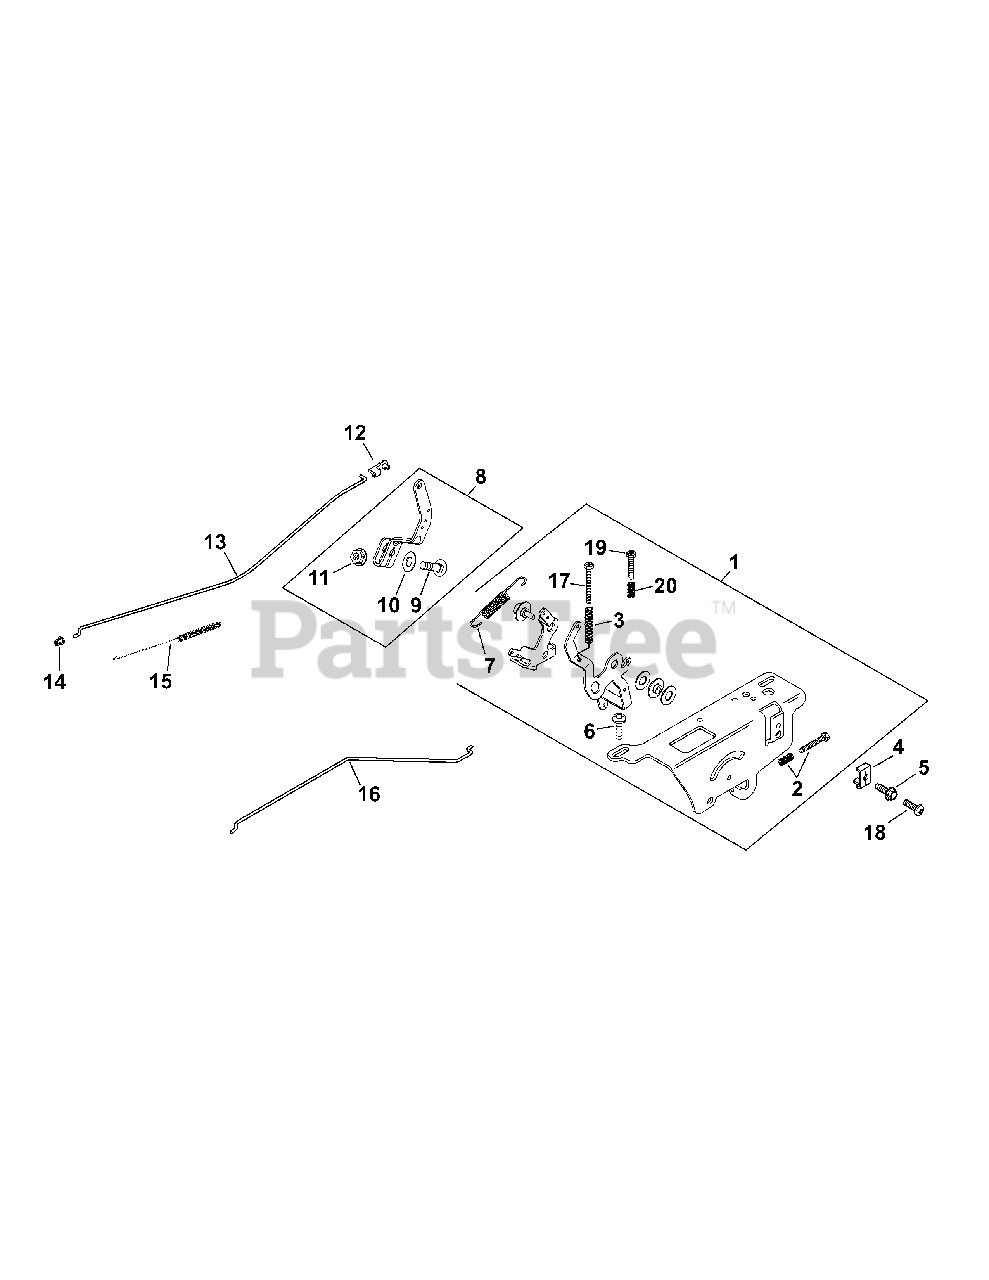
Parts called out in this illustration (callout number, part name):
1	Speed Control Assembly Kit
2	Idle Adj. Screw & Spring Kit
3	Speed Control Spring
4	Cable Clamp
5	Flg. Thd. Frm. Screw, M5 X 0.8 X 16
6	Lbd. Skt. Screw, M6 X 1.0 X 20
7	Governor Spring
8	Governor Assembly Lever (Inc. 9-11)
9	Rd. Hd. Sq. Nck. Bolt, 1/4-20 X 1
10	Int. Tooth Lock Washer, 1/4
11	Hex Flange Nut, 1/4-20
12	Throttle Linkage Bushing
13	Throttle Linkage
14	Linkage Retaining Bushing
15	Linkage Spring
16	Choke Linkage
17	Phl. Thd. Frm. Screw, M4 X 0.7 X 38
19	Phl. Thd. Frm. Screw, M4 X 0.7 X 25
20	Speed Control Spring (Short)
